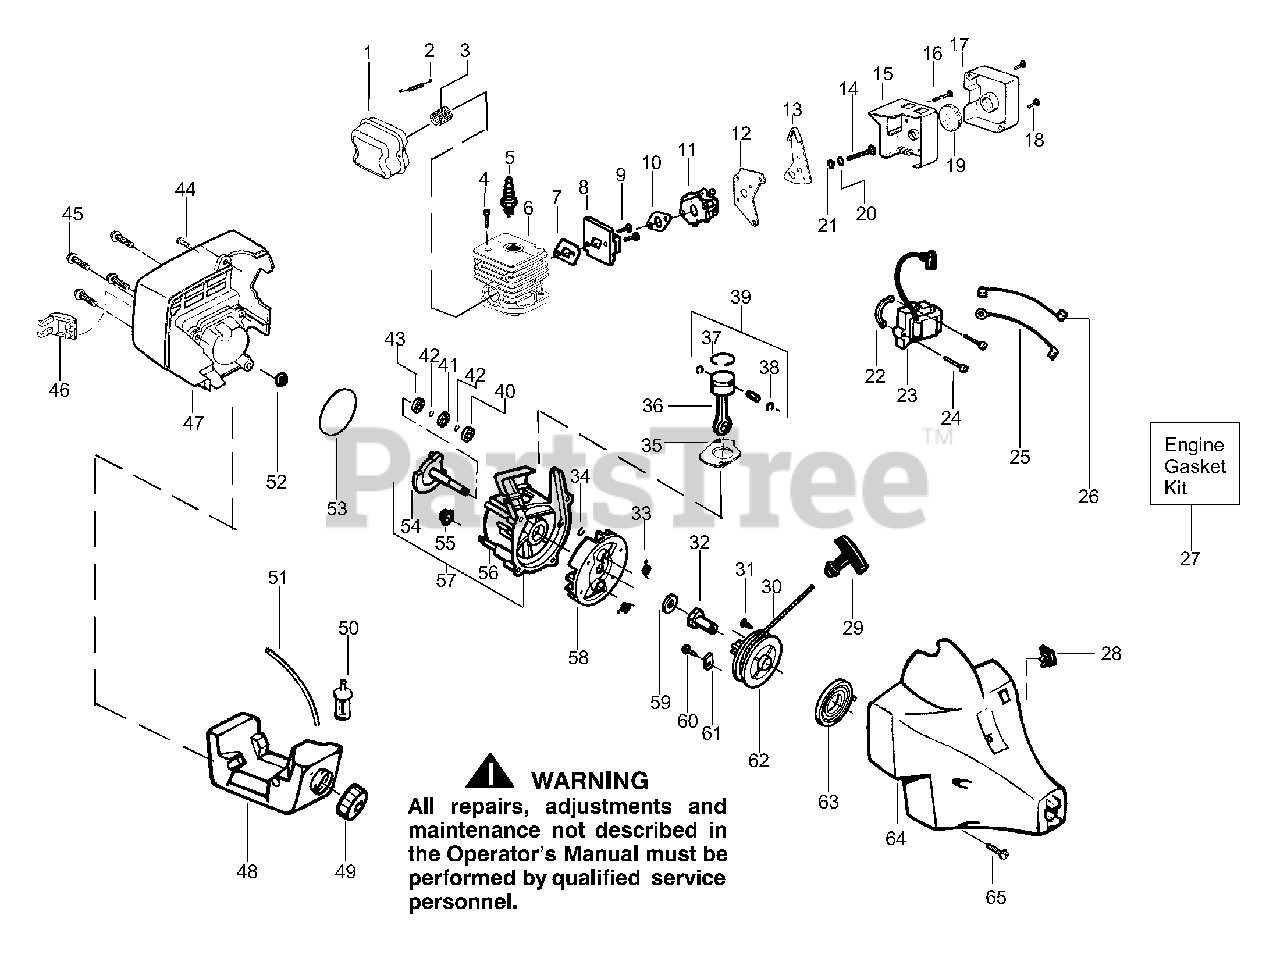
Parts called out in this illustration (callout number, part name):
1	Kit-Muffler
2	Muffler Spring
3	Screen-Spark Arrestor
4	Screw-Cylinder
5	Spark Plug (RCJ-8Y)
6	Kit-Cylinder
7	Gasket-Cylinder/Carb.
8	Kit-Carb. Adapter
9	Screw-Carb. Adptr.
10	Gasket-Carb.
11	Kit-Carb. Ass'y.
12	Choke Plate
13	Choke Shutter
17	Air Filter Cover
18	Screw-Air Box
19	Air FIlter Foam
20	Choke Spacer
22	Spacer-Ignit. Module
23	Ignition Module
24	Screw-Ignit. Module
25	Ground Wire Ass'y.
26	Lead Wire Ass'y.
27	Kit-Engine Gasket
28	Switch-Momentary
29	Starter Handle
30	Kit-Rope
32	Drive Coupling
33	Spring Starter Dog
34	Ret. Ring/C'shaft
35	Gasket-Cylinder
36	Assy. Connecting Rod
37	Piston Ring
38	Piston Pin Retainer
39	Kit-Piston
40	Outer Bearing
41	C'case Seal
42	Ret. Ring-C'case
43	Inner Bearing
44	Screw-Shd/Fan Hsg
45	Screw
46	Guard-Muffler
47	Rear Shroud
48	Assy-Fuel Tank
49	Fuel Cap Assy.
50	Fuel Pickup Assy
51	Kit-Fuel Line
52	Isolator-Shroud
53	O-Ring - Crankcase
54	Crankshaft Ass'y.
55	Isolator-Crankcase
56	Crankcase Assy.
57	C'case/C'shaft Assy.
58	Flywheel Ass'y.
59	Washer-Flat
60	Screw-Pulley
61	Retainer-Pulley
62	Kit-Starter Pulley
63	Starter Spring
64	Assy.-Fan Hsg.
65	Screw
